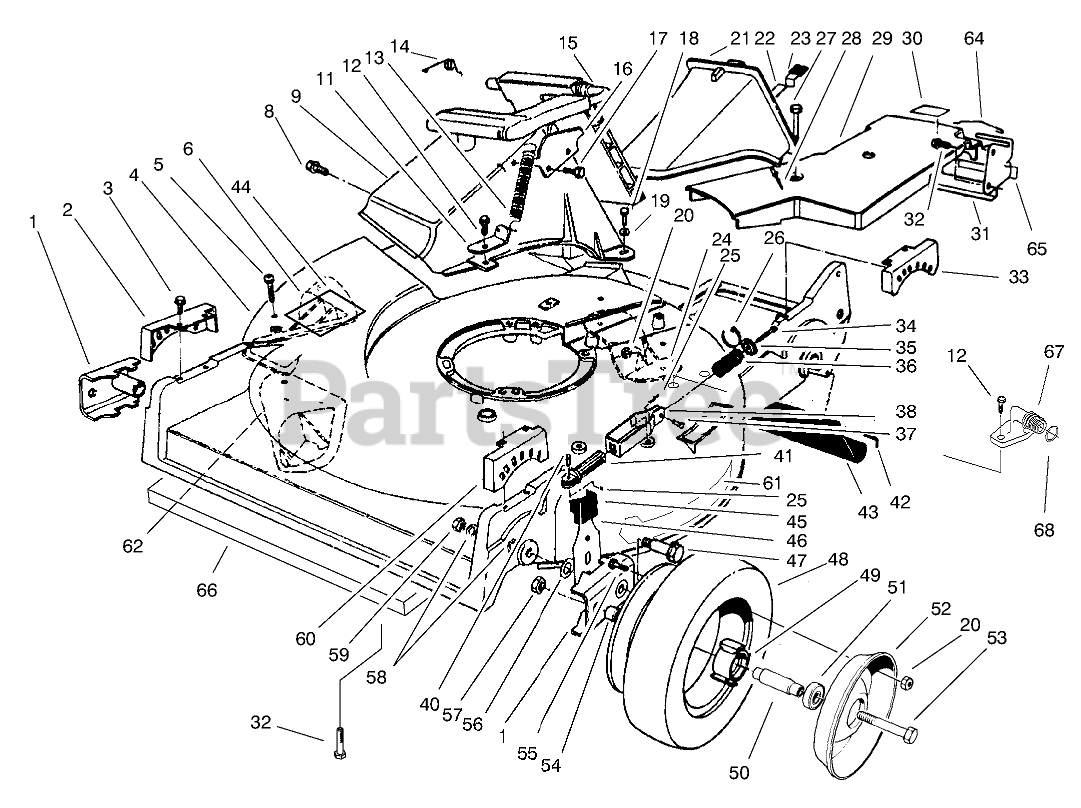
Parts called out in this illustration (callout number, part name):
1	ARM-PIVOT, FRONT
2	QUADRANT-FRONT, RH
3	SCREW-HWHTF
4	Housing-Commercial (Incl. Ref. #5, 6, 12, 24, 32, 44, 62, & 66-68) (Incl. Ref. #28 pg. 4)
5	SCREW-PPH
6	KICKER-RH
8	SCREW AND WASHER ASM
9	TUNNEL-DISCHARGE
11	BRACKET-SPRING
12	SCREW-HWH
13	SPRING-DOOR
14	RETAINER-DOOR
15	DISCHARGE DOOR ASM
16	LATCH-PLATE
17	SCREW-PLASTITE
18	SCREW-HH
19	WASHER-FLAT
20	NUT-LOCK, NI
21	Plug-Discharge (Incl. Ref. #22, 23, & 28)
22	LATCH-PLUG, DISCHARGE
23	GRIP-LATCH
24	KICKER-REAR
25	PIN-COTTER
26	TIE-CABLE
27	SCREW-HHFTF
28	RIVET-HEAD, FLAT
29	BELT COVER
30	DECAL-GREASE
31	BRACKET-ADJUSTMENT, TRACTION
32	SCREW-HWHTF
33	QUADRANT-REAR, LH
34	SCREW-HWHTF
35	RETAINER-SPRING
36	SPRING
37	PIN-CABLE
38	Bracket-Spring
40	PIN-SPRING
41	GUIDE-SPRING
42	ROD-SHIELD
43	SHIELD-TRAILING
44	DECAL-DANGER
45	KNOB-ARM
46	FRONT SPRING ARM ASM
47	BOLT-WHEEL
49	HUB-BEARING
50	SPACER-BEARING
51	BEARING-WHEEL
52	Wheel-Half
53	SCREW-HH
54	SPACER-WHEEL
55	SCREW-HH
56	WASHER-THRUST
57	NUT-LOCK, CONE
58	WASHER
59	NUT-LOCK
60	QUADRANT-FRONT, LH
61	DECAL-RECYCLER
62	KICKER-FRONT
64	RETAINER-CABLE
65	DECAL-POSITION, GEAR
66	Shield-front
67	FITTING-WASHOUT
68	O-RING
